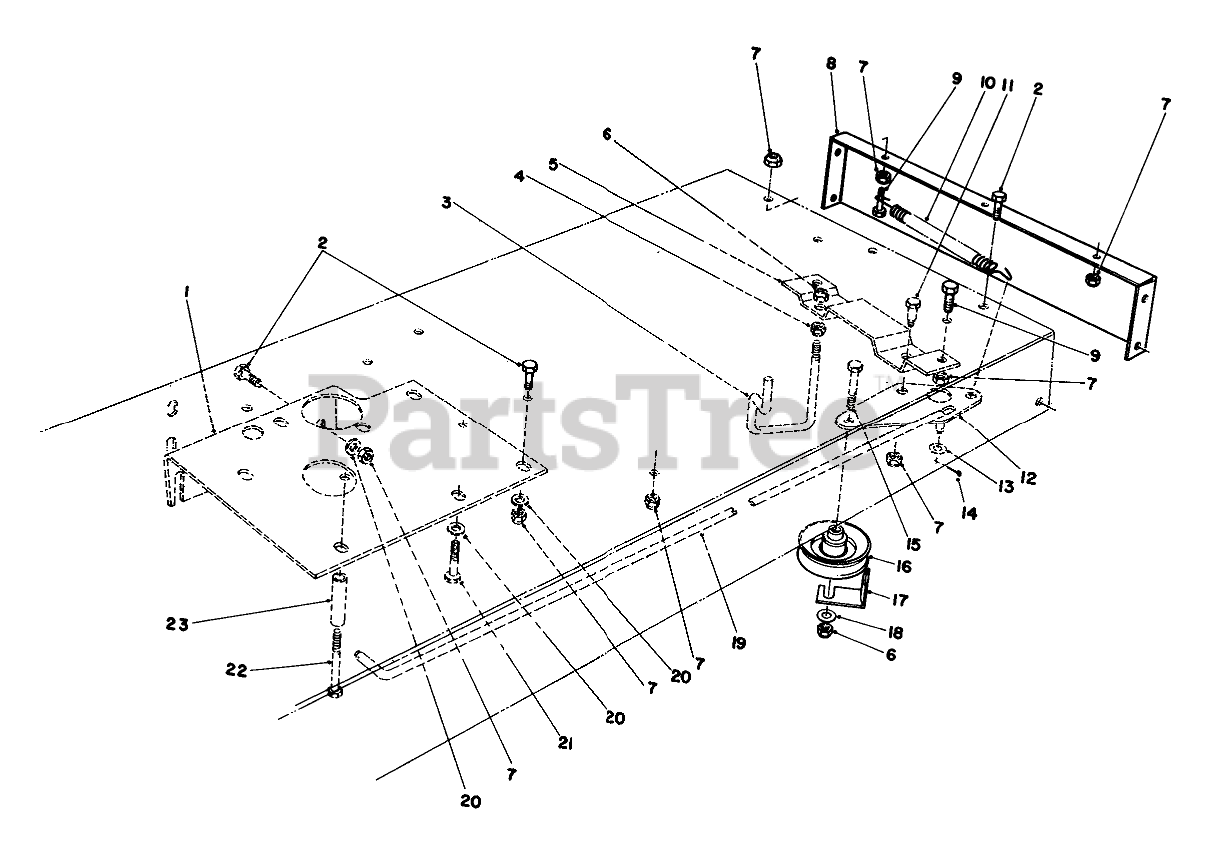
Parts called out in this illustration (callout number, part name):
1	REINF PLATE R
2	SCREW-HH
3	BELT GUIDE
4	NUT-LOCK, SIDE
5	TRACT SUPP BRKT B
6	NUT-LOCK, CONE
7	NUT-LOCK, NI
8	REAR FRAME R
9	SCREW-HH
10	TRACTION SPRING
11	BOLT-SHOULDER
12	TRACTION PIVOT BRKT
13	WASHER-FLAT
14	PIN-COTTER
15	SCREW-HH
16	PULLEY-IDLER
17	RETAINER-BELT
18	WASHER-FLAT
19	TRACTION ROD
20	WASHER-PLAIN
21	Screw-HH
22	SCREW-HH
23	OUTER TUBE SPACER
